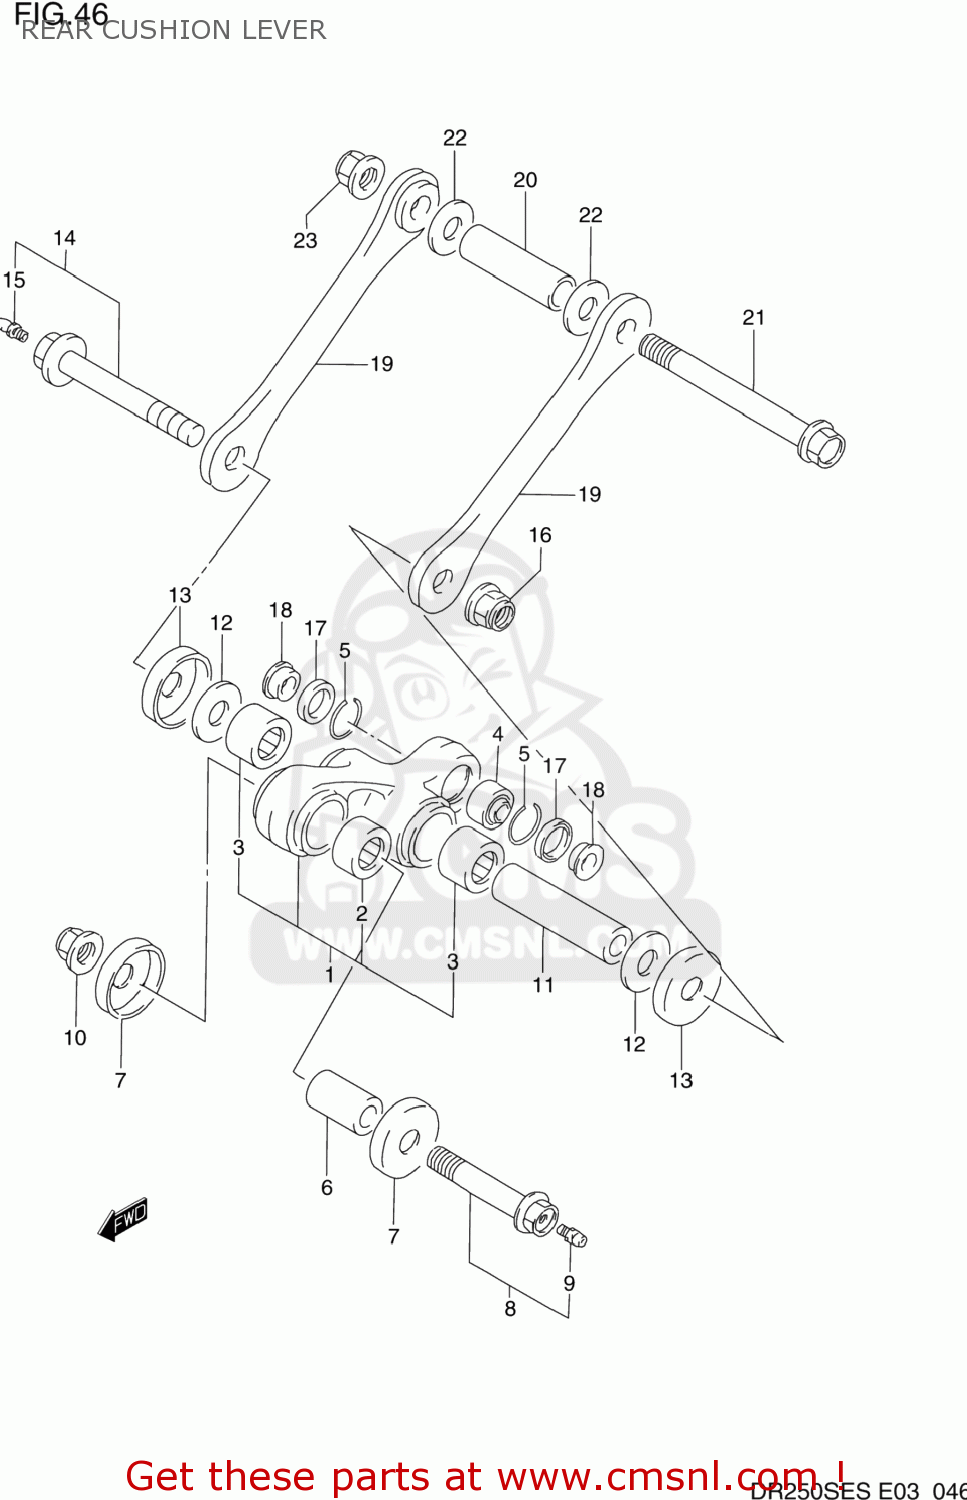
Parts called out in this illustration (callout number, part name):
1	LEVER SET,RR CUSHION
2	BEARING(20X27X32)
3	BEARING(20X27X23.5)
4	BEARING,RR CUSHION LEVER
5	RING,STOPPER
6	SPACER,RR CUSHION LEVER FR
7	SEAL,REAR CUSHION LEVER
8	BOLT,RR CUSHION LEVER FR
9	GREASE NIPPLE
10	NUT 12MM
11	SPACER,RR CUSHION LEVER CTR
12	WASHER
13	SEAL,RR CUSHION LEVER
14	BOLT,RR CUSHION LEVER CTR
15	GREASE NIPPLE
16	NUT
17	SEAL,OIL(17X24X3)
18	COLLAR
19	ROD,RR CUSHION
20	SPACER,RR CUSHION ROD
21	BOLT,RR CUSHION ROD
22	WASHER
23	NUT
